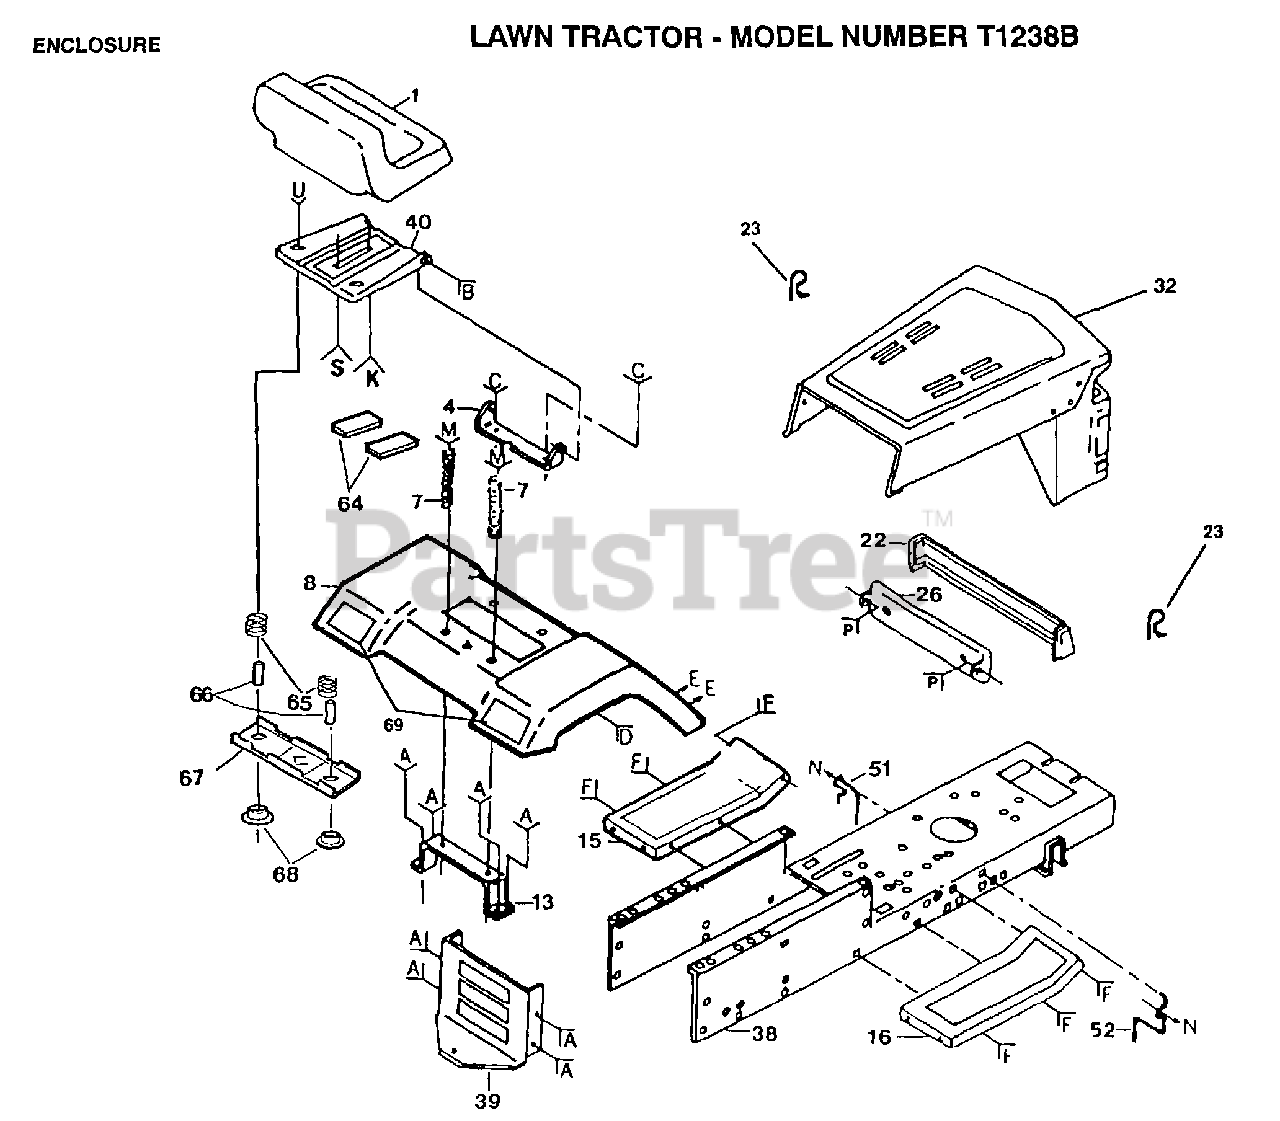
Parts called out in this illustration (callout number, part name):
7	SPRING COMPRESSIO
15	FOOTREST LH
16	FOOTREST
32	HOOD&GRILL ASSY
38	CHASSIS ASS'Y
51	BELT GUIDE
52	BELT GUIDE
64	STRIP FORM
65	SPRING COMPRESSED
66	SPACER SPLIT
67	BRKT SWITCH
68	BUSHING
69	REFLECTOR-TAIL YT
